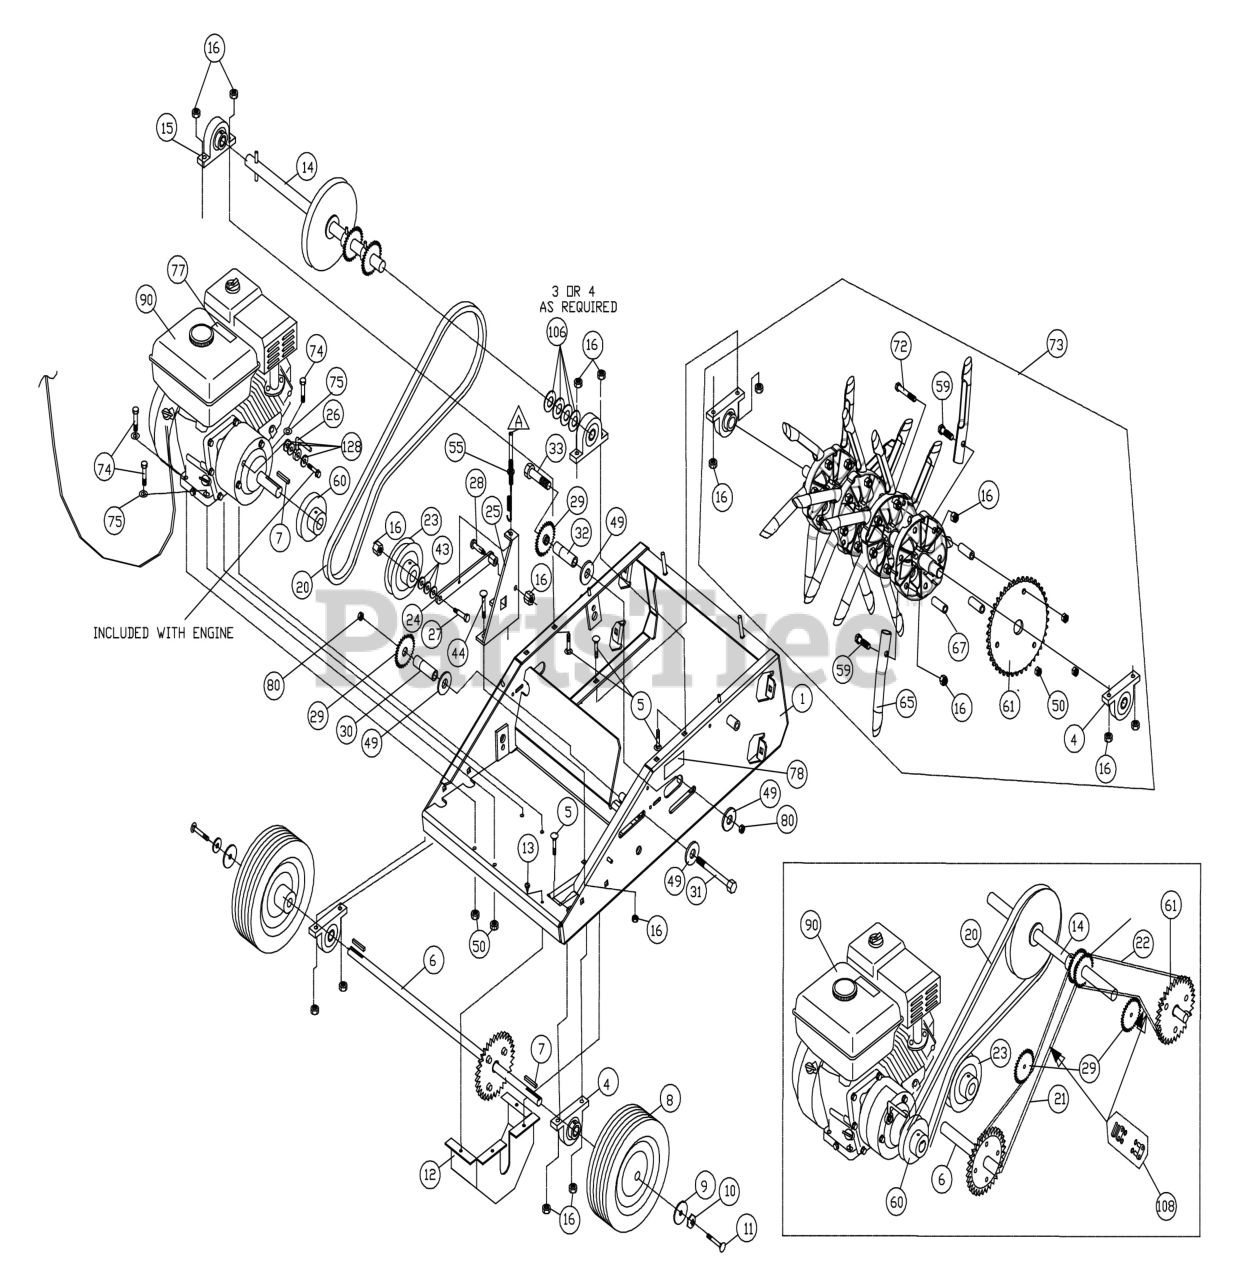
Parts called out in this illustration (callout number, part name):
1	FRAME WA AE401
4	BEARING 3/4" CAST P BLOCK
5	BOLT CARRIAGE 3/8"-16 X 1 1/2" ZP
6	DRIVE LOWER WA AE401
7	KEY 3/16" SQ X 1 1/4"
8	WHEEL 10.0" SEMI PN. RIBBED W/3/4" HUB
9	WASHER FLAT FENDER 5/16
10	WSHR-STL, BLV .322" X .938" X .072" MZ
11	SCREWCAP 5/16"-18 X 1" HCS ZP
12	SEE: 360354
13	SCREW SELF TAP 1/4"-20 X 5/8" HWH TYPE F
14	SHAFT DRIVE WA AE401
15	BEARING 1" PILLOW BLOCK
16	NUT-HEX-NYLK, FLG .375"-16 ZP
20	BELT 4L X 43" POWERATED
21	CHAIN #40 X 94 PITCH O-RING
22	CHAIN #40 X 76 PITCH O-RING
23	PULLEY IDLER 4.5" FH-6412-8
24	ARM IDLER WA HW
25	BRACKET MOUNT IDLER
26	SEE: 360220
27	SCREWCAP 3/8"-16X2" HCS ZP
28	BOLT SHOULDER 1/2" X 1"
29	SPROCKET IDLER 17T X 5/8" BORE
30	SPACER SPROCKET IDLER 2.5
31	SCREWCAP 1/2"-13 X 4" HCS ZP
32	SPACER SPROCKET IDLER 1.3
33	SCREWCAP 1/2-13 X 3" Z/P
43	WASHER 3/8"SAE 13/32"X13/16"X1/16"
44	BOLT CARRAIGE 3/8-16 X 1" ZP
49	WASHER 1/2"FC9/16"X1 3/8"X7/64"
50	NUT-HEX-NYLK, FLG .3125-18 ZP
55	CABLE CLUTCH ASSY AE401
59	SCREWCAP 3/8" - 16 X 1/2" HCS ZP
60	PULLEY 3.25" OD X 3/4" BORE
61	SPROCKET 42T, 1" CENTER HOLE
65	TINE CORING 3/4" X 3"
67	SPACER SPROCKET AE REEL
72	SCREWCAP 5/16"-18X2 1/2" HCS ZP
73	SHAFT TINE DRIVE
74	SCREWCAP 5/16"-18X1 1/2" HCS ZP
75	WASHER 5/16" FLATWASHER Z/P
77	LABEL HOT ENGINE
78	LABEL DANGER
80	NUT LOCK 1/2"-13 NYLON INSERT
90	ENGINE, VANGUARD 203CC W/6:1 AT 3
106	WASHER FLAT 1.75 OD X 1.06 ID X 0.100 ZP
108	LINK MASTER #40 O-RING
128	WASHER 1/4" FLAT Z/P
